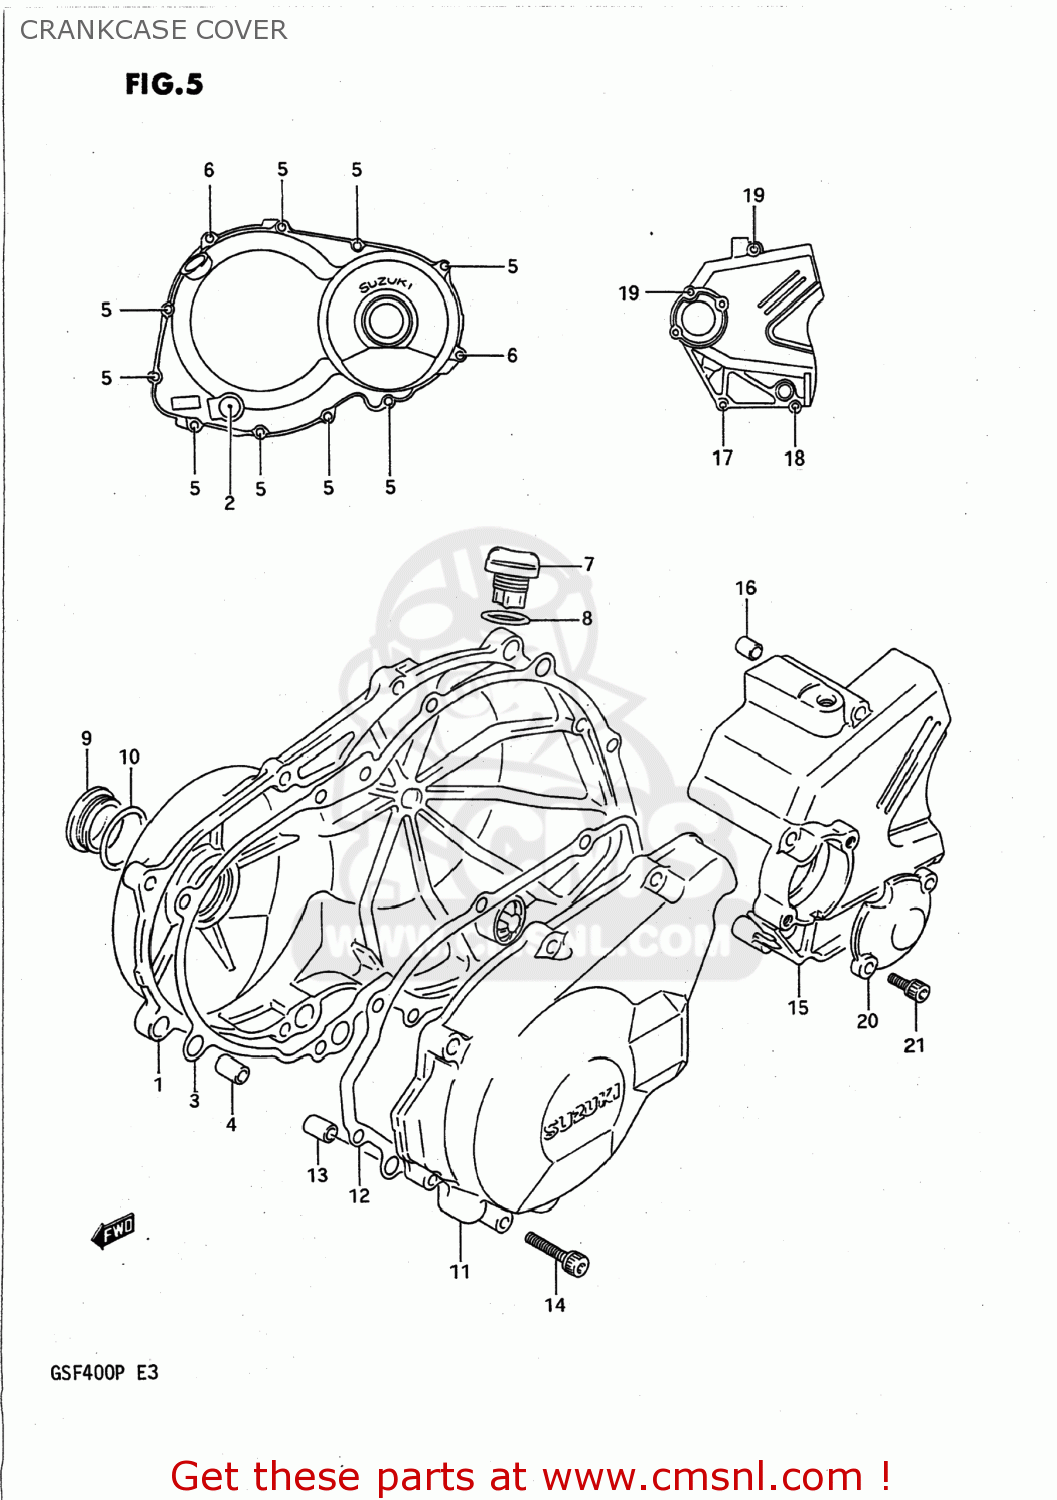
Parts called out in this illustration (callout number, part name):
1	COVER,CLUTCH
2	LENS,OIL LEVEL CHECK
3	GASKET,CLUTCH COVER (NAS)
4	PIN
5	BOLT
6	BOLT
7	PLUG,OIL FILLE
8	O RING(D:3.1,ID:16.8)
9	PLUG
10	O RING(D:3.1,ID:32.7)
11	COVER,STARTER GEAR
12	GASKET,MAGNETO COVER (NAS)
13	PIN (11X20)(SUS)
14	BOLT
15	COVER,SPROCKET
16	PIN
17	BOLT
18	BOLT
19	BOLT
20	CAP,CLUTCH RELEASE ADJUST
21	BOLT
